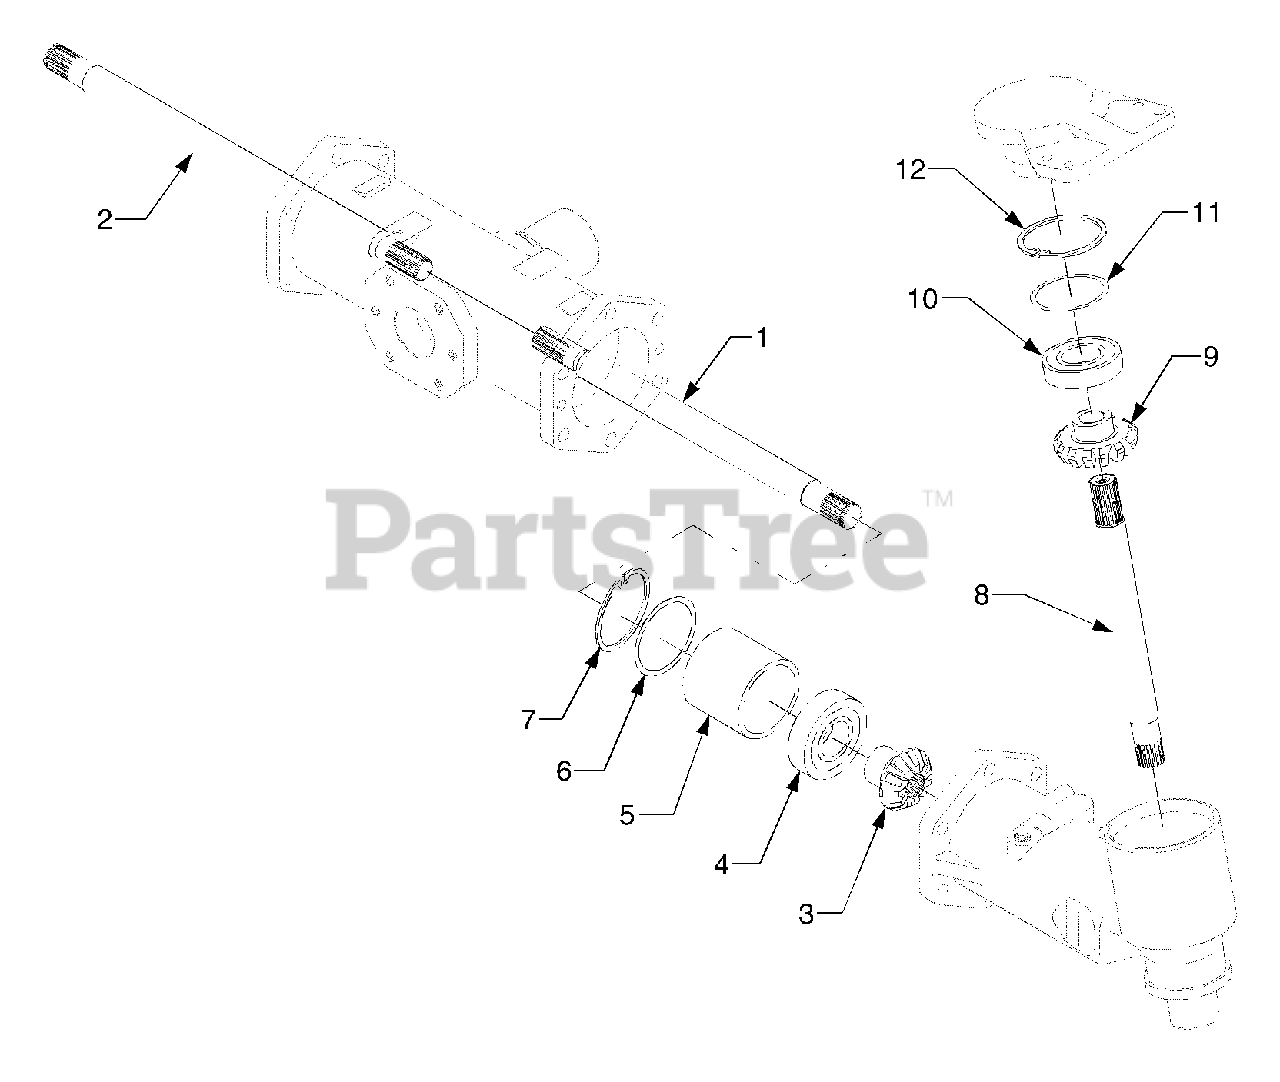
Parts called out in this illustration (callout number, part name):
1	Shaft, Differential Gear (LH)
2	Shaft, Differential Gear (RH)
3	Gear, 11 Bevel
4	Bearing, Ball
8	Shaft, Bevel Gear
9	Gear, 16 Bevel
10	Bearing, Ball
